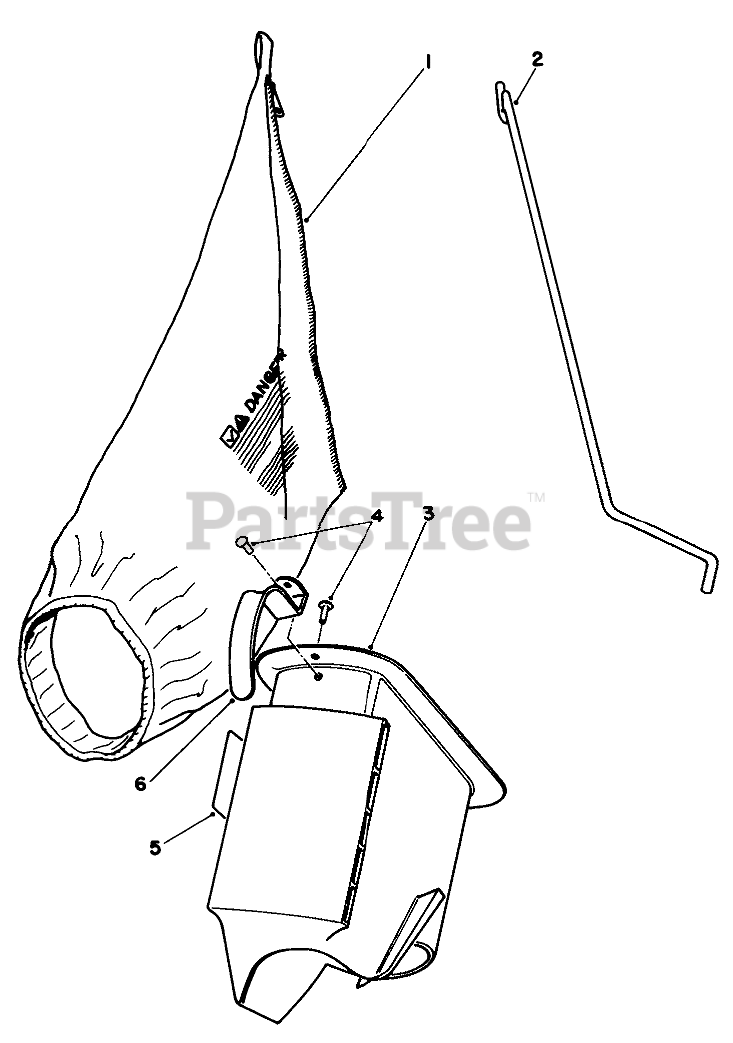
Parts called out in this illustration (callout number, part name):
1	BAG REPLACMNT44-0540
2	BAG ROD
3	Grass Chute (Incl. Ref. #4 & 6)
4	RIVET 3/16 X 7/16
5	BAG CHUTE DECAL
6	HANDLE-GRASS CHUTE
